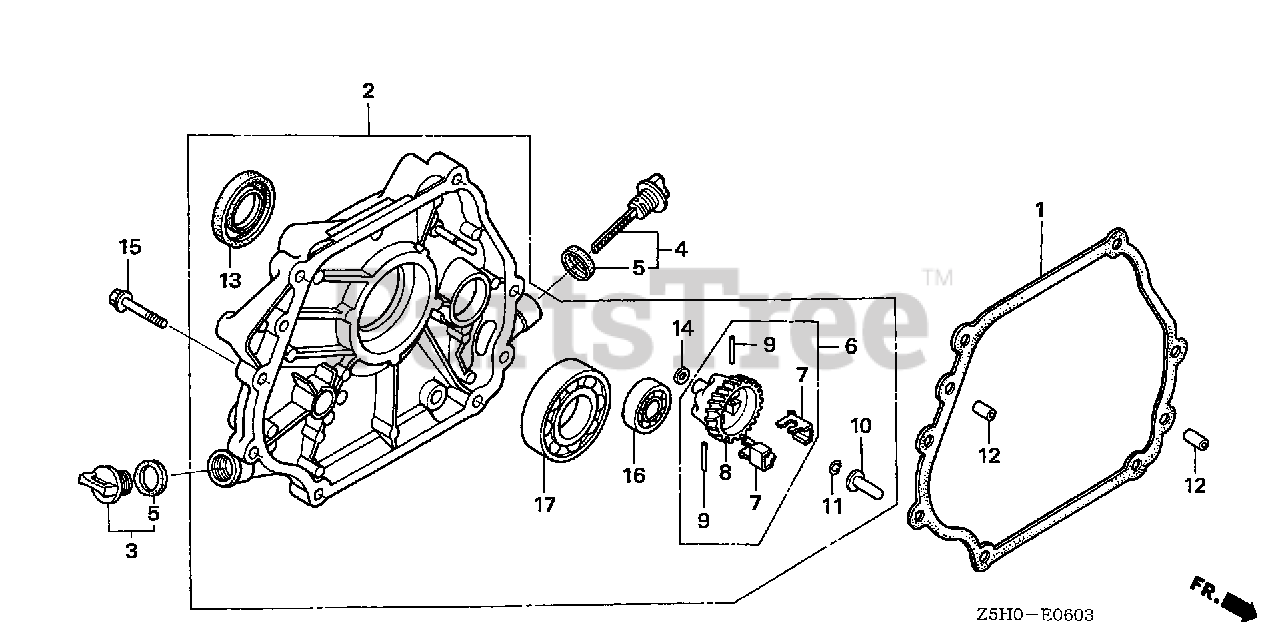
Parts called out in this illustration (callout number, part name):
1	GASKET, CASE COVER
2	COVER ASSY., CRANKCASE
3	CAP ASSY., OIL FILLER
4	CAP ASSY., OIL FILLER
5	GASKET, OIL FILLER CAP
6	GOVERNOR ASSY.
7	WEIGHT, GOVERNOR
8	HOLDER, GOVERNOR WEIGHT
9	PIN, GOVERNOR WEIGHT
10	SLIDER, GOVERNOR
11	CLIP, GOVERNOR HOLDER
12	PIN, DOWEL (8X12)
13	OIL SEAL (30X46X8)
14	WASHER, PLAIN (6MM)
15	BOLT, FLANGE (8X35)
16	BEARING, RADIAL BALL (6202)
17	BEARING, RADIAL BALL (6206)
